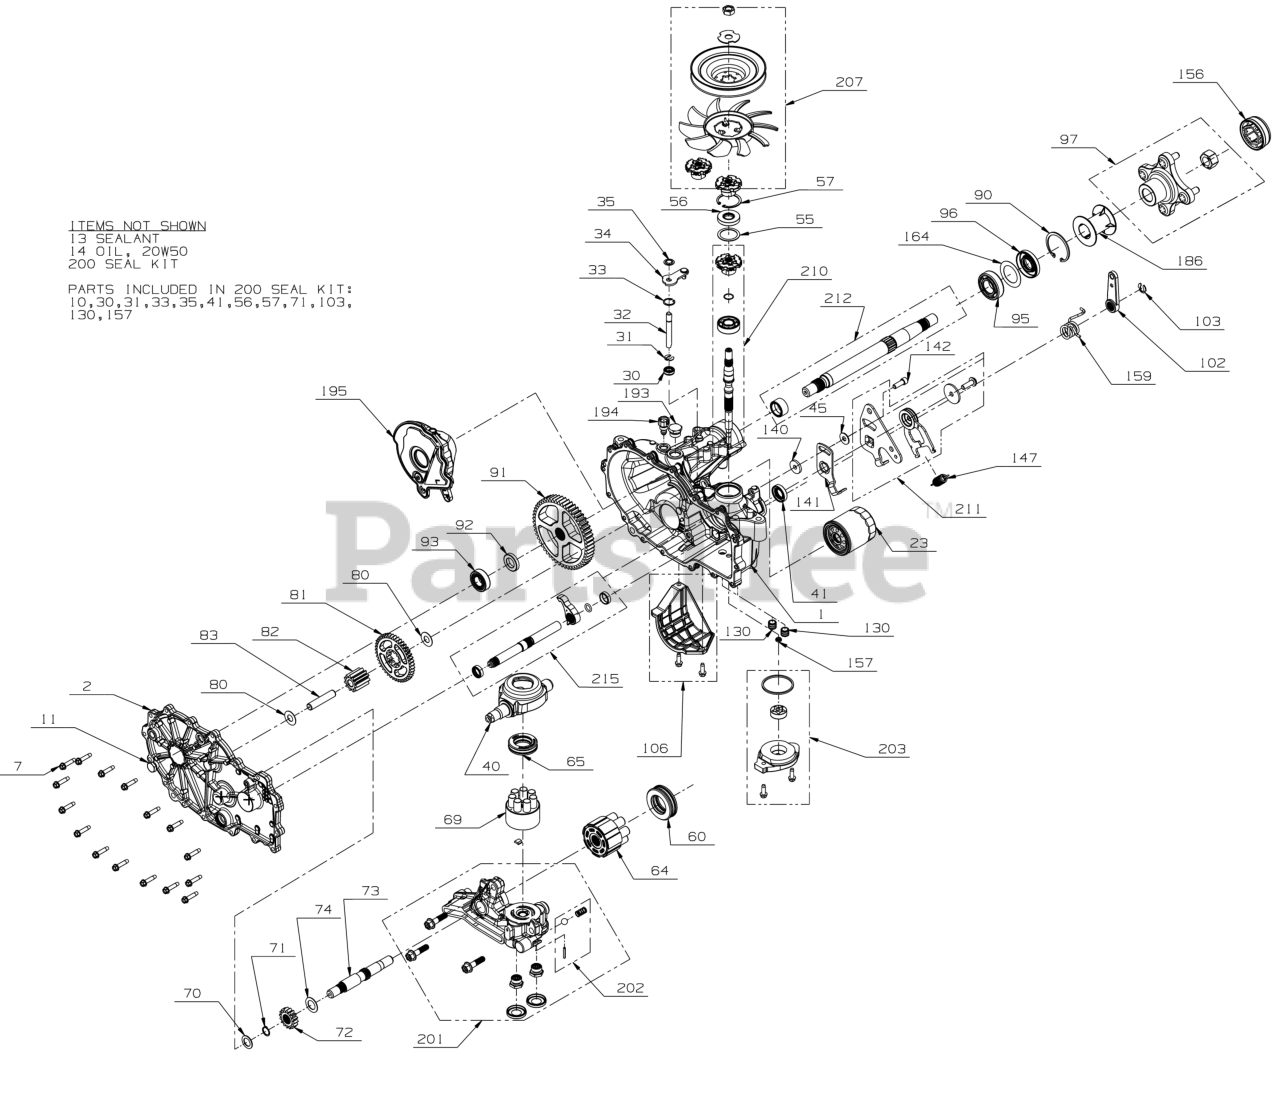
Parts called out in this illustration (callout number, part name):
1	MAIN HOUSING KIT (LH)
2	SIDE COVER KIT (LH)
7	SCREW-WASHER HEAD
11	VENT PLUG
13	SEALANT-HOUSING
23	OIL FILTER
30	SEAL-LIP .375 X .75 X .25
31	RETAINING RING
32	BYPASS RODS
33	RETAINING RING
34	ARM-BYPASS
35	RETAINING RING
40	SWASHPLATE-TRUNNION
45	FLAT WASHER
55	WASHER 1.23X1.56X
57	RETAINING RING
60	THRUST BEARING
64	CYLINDER BLOCK ASSEMBLY
65	THRUST BEARING
69	BLOCK KIT-7 PISTON
70	FLAT WASHER
71	RETAINING RING
72	GEAR-16 T
73	MOTOR SHAFT
74	MOTOR SHAFT WASHER
81	GEAR-43 T
82	GEAR-11 T
83	PIN-JACKSHAFT
90	RETAINING RING
91	GEAR-54 T
92	SPACER .75X1.32X.257
93	BALL BEARING
95	BALL BEARING
97	HUB-4 BOLT WHEEL
102	BRAKE LEVER
103	RETAINING RING
106	FILTER GUARD KIT
130	TUBE-CHARGE TRIPLE O-RING
140	SPACER .32 x 1.005 x .179
141	ARM-NEUTRAL (LH)
142	SCREWS KIT-RTN
147	EXTENSION SPRING
156	COVER-NUT
157	KIT-GEROTOR SEAL
159	TORSION SPRING CW
186	TUBE-AXLE 2.03
193	PLUG 3/4-16
194	BREATHER FITTING 9/16-18
195	EXPANSION TANK (LH)
201	SECTION ASSEMBLY-CENTER
202	KIT-CHARGE RELIEF
203	CHARGE KIT
207	FAN & PULLEY KIT
209	PULLER KIT-HUB
210	INPUT SHAFT KIT
211	KIT - RETURN CCW
212	SHAFT KIT-AXLE
215	OUTPUT SHAFT KIT
